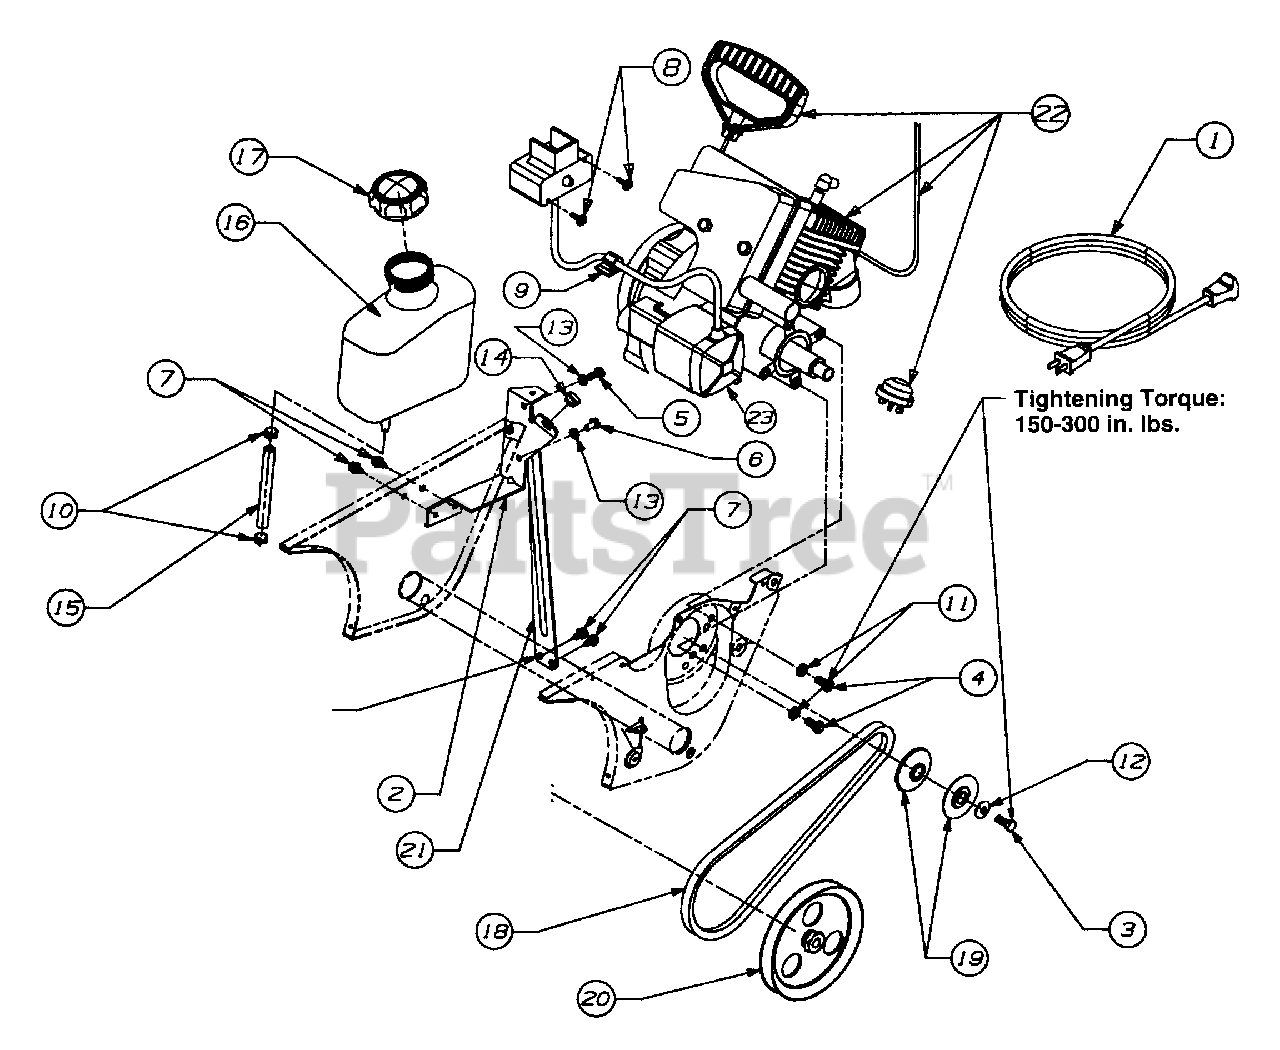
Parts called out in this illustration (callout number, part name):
1	Cord-Ext. 110V 2 Prong
2	Gas Tank Support Bracket
3	Screw-Hex
4	Screw-Hex
5	Screw-Hex
6	Screw-Hex
7	Screw-Hex
8	Screw-Hex
9	Clamp-Mounting
10	Clamp-Hose
11	Washer-Lock
12	Washer-Bell
13	Washer-Lock
14	Bushing
15	Hose-Fuel Line, 16"
16	Tank-2 Quart
17	Fuel Cap
18	V-Belt
19	V-Pulley Half
20	Pulley
23	Starter Kit
